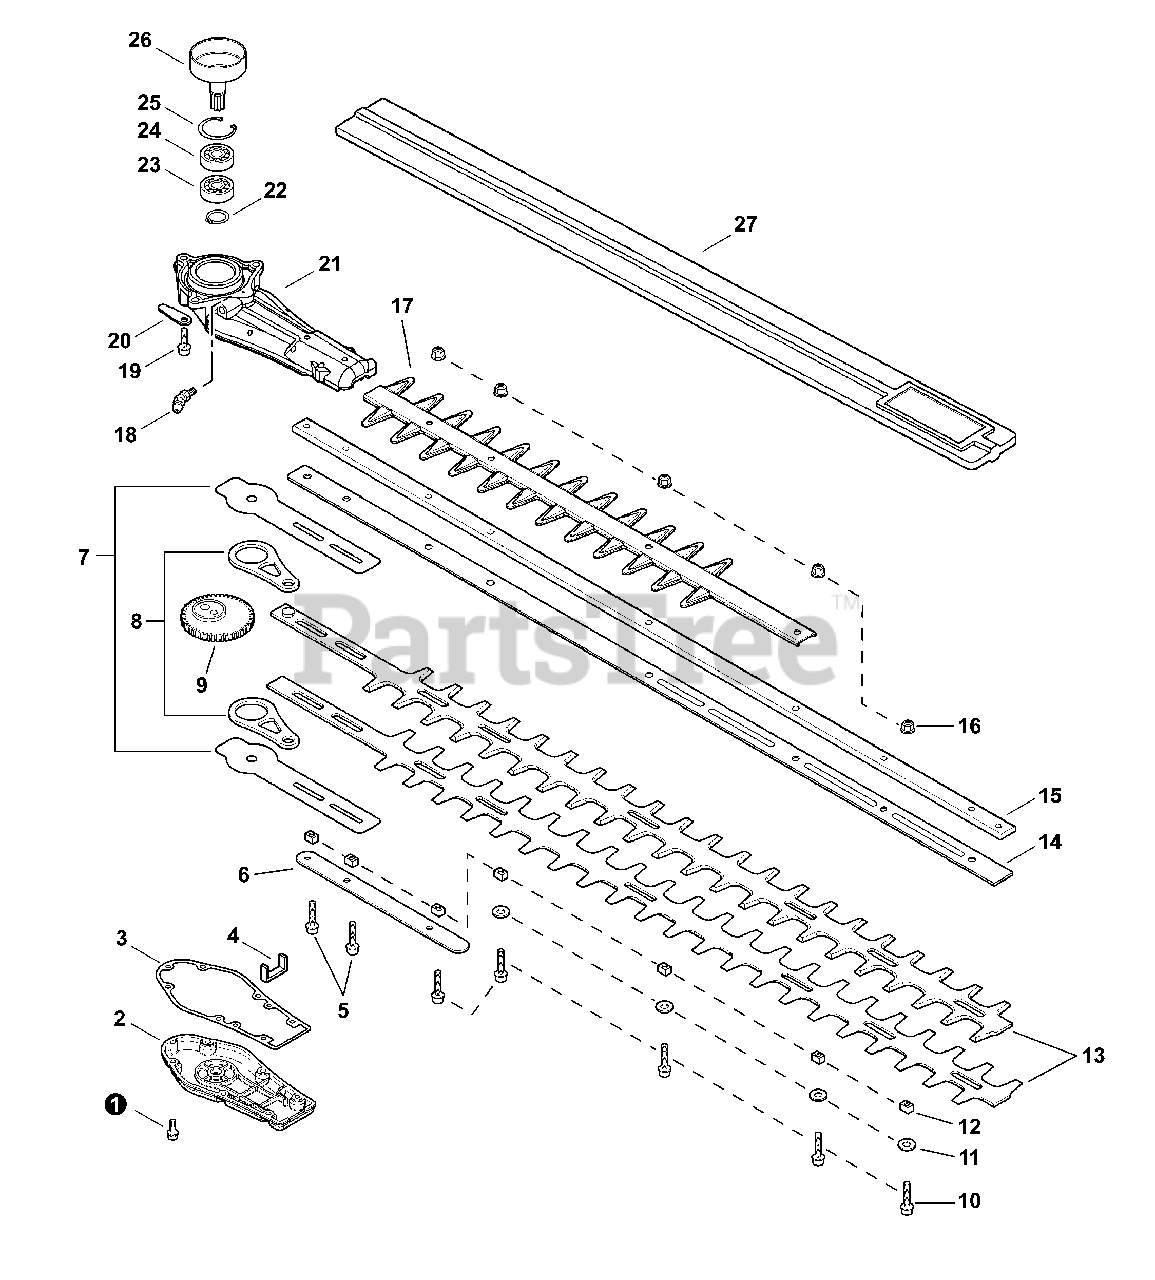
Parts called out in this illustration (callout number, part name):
1	BOLT 4×16
2	COVER, GEAR CASE
3	GASKET, GEAR CASE
5	BOLT 5×25
6	PLATE, EYE
7	PLATE, EYE
8	ROD, CONNECTING
9	GEAR, SPUR
10	BOLT, FLANGE 5×22
11	WASHER 5
12	GUIDE, BLADE 5
14	SUPPORT, BLADE
15	SUPPORT, BLADE
16	NUT, FLANGE M5
17	GUARD, CUTTER BLADE
18	FITTING, GREASE
19	BOLT, FLANGE 6×20
21	CASE, GEAR
22	RING, SNAP 14
23	BEARING, BALL 6202
24	BEARING, BALL 6202 DDU
25	RING, SNAP 35
26	DRUM, CLUTCH
27	SCABBARD
